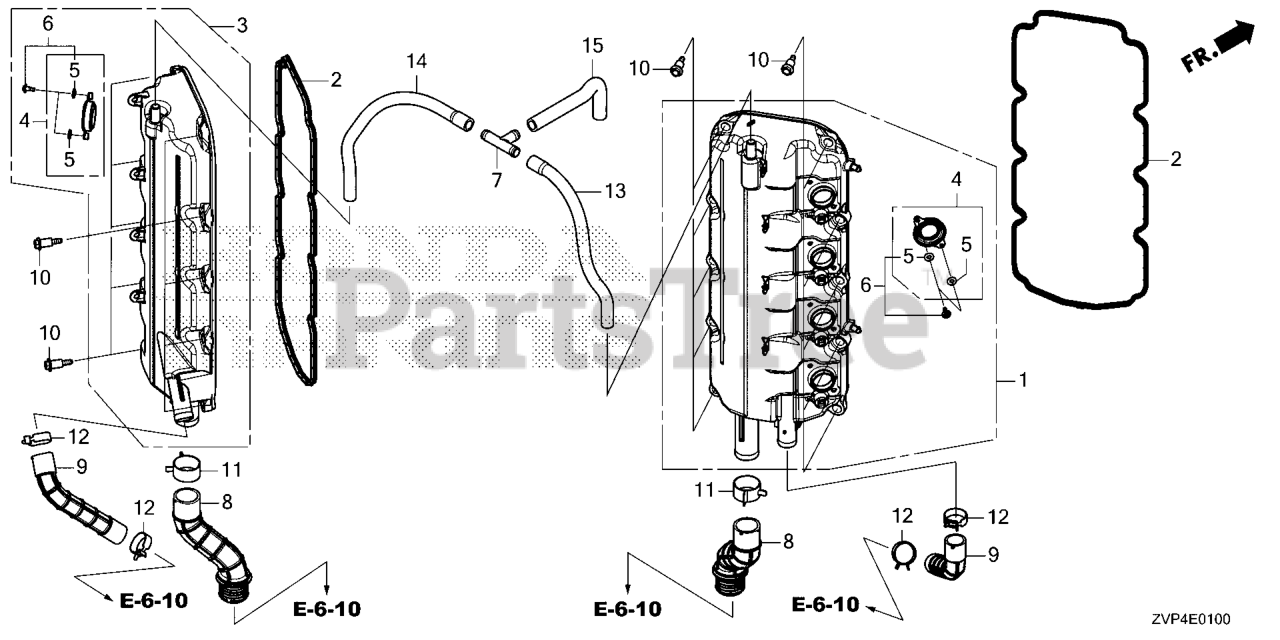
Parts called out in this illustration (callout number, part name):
1	COVER, CYLN HEAD R
2	PKG, HEAD COVER
3	COVER, CYLN HEAD L
4	SEAL SET, HEAD COVER PLUG TUBE
5	WASHER, SEALING
7	JOINT (THREE-WAY)
8	TUBE, OIL
9	TUBE, BREATHER
10	BOLT, HEAD COVER
11	CLAMP, TUBE (D32.5)
12	CLAMP, TUBE (D25.0)
13	TUBE, BREATHER A
14	TUBE, BREATHER B
15	TUBE, BREATHER C
